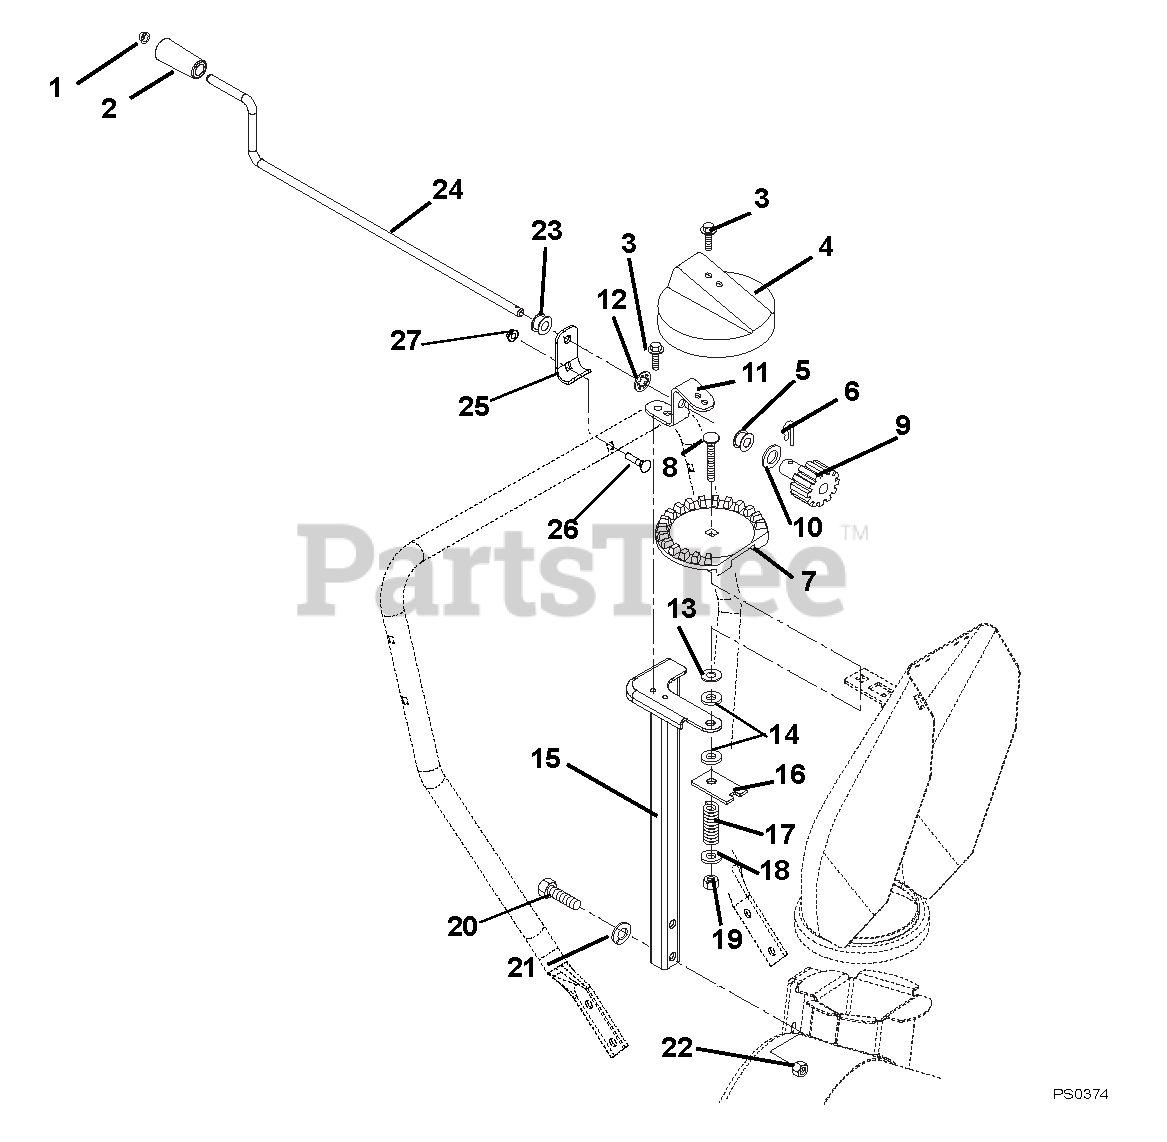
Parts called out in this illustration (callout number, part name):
1	CAP, 3/8 ROD YWZC
2	KNOB, CHUTE CRANK
3	@SCR-TAP .25-20X.50 HWH TR YWZ
4	GEAR COVER
5	BUSHING, POLYLINER-.63 SNAPIN
6	PIN, SPRING CLIP
7	CHUTE GEAR
8	@BLT-RDHDSQNK .38-16X2.50 G5YZ
9	PINION GEAR W/BRACKET
10	WSHR-THRST .625 X 1.0 X .03
11	BRACKET, PINION GEAR
12	PUSHNUT .625
13	WSHR-FL-STL .380X1.50X.062 YWZ
14	FRICTION WASHER
15	WELDMENT, CHUTE PEDESTAL
16	PLATE, FRICTION
17	SG-COMP .187X.56X1.62
18	@WSHR-FL-STL.406X.812X.065 YWZ
19	@NUT-LK-CTR .38-16 YWZC
20	@BLT-HEX .38-16X1.75 GR5 YWZC
21	@WSHR-LK .38X.094 REG YWZC
22	@NUT-LK-TOP-FLG .38-16 YWZC
23	BUSHING, POLYLINER-.38 SNAPIN
24	ROD, CHUTE CRANK
25	BRACKET, CRANK SUPPORT
26	@BLT-RDHDSQNK .31-18X1.50 G5YZ
27	@NUT-LK-TOP-FLG .31-18 YWZC
